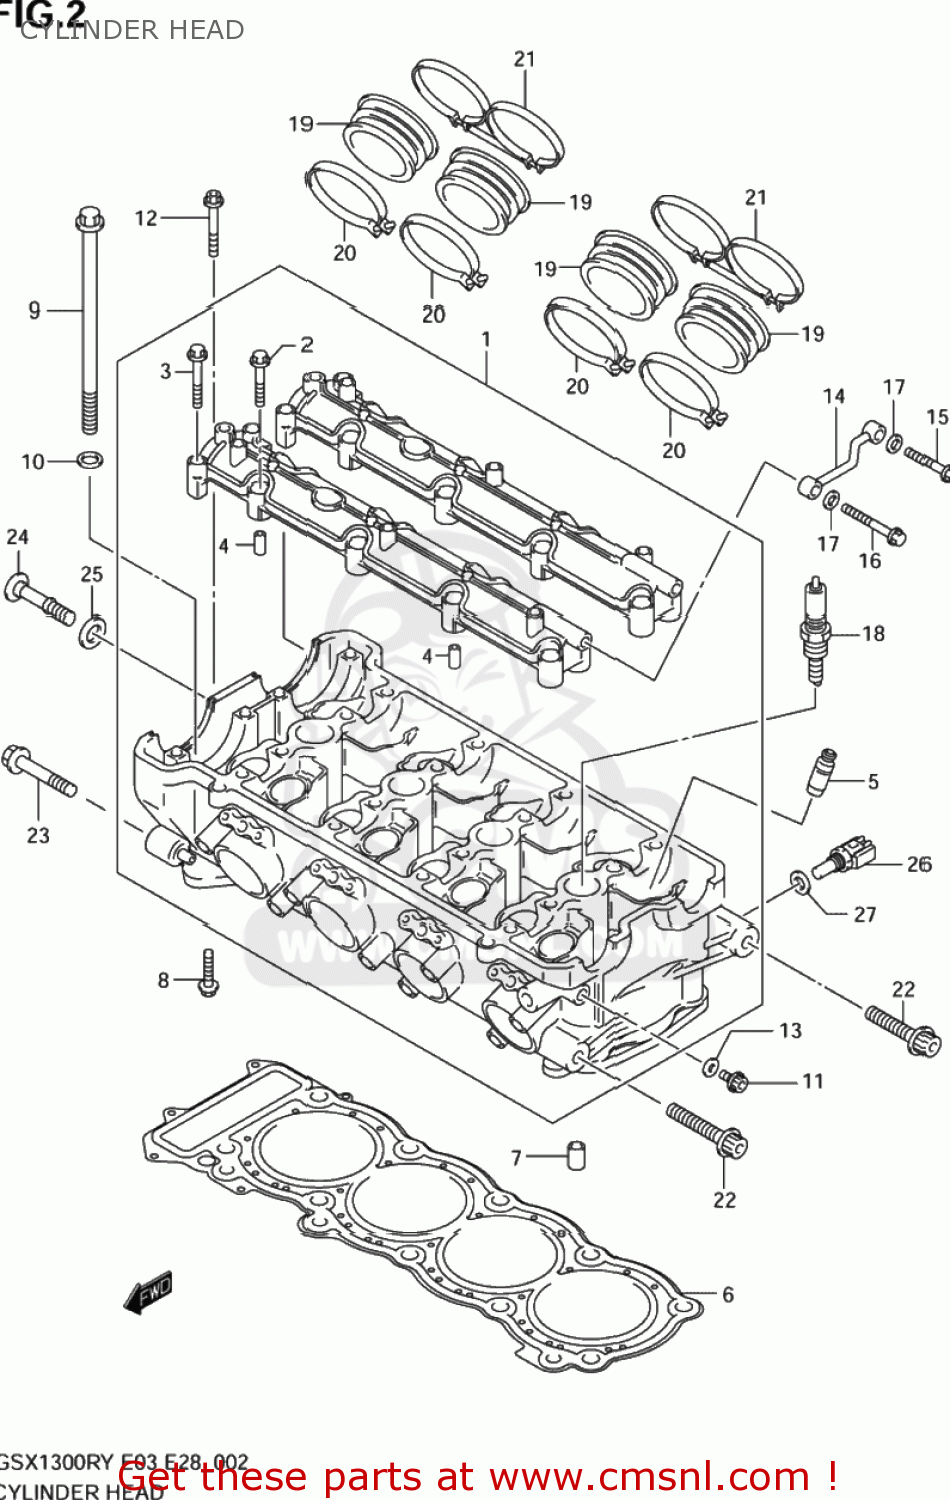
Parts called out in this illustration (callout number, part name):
1	HEAD ASSY,CYLINDER
2	BOLT(6X39)
3	BOLT(6X45)
4	PIN(6.2X8X16)
5	GUIDE,VALVE
6	GASKET,CYLINDER HEAD (NAS)
7	PIN
8	BOLT
9	BOLT(10X175)
10	WASHER(10.5X19X2)
11	BOLT
12	BOLT,CYL.OIL P
13	GASKET(5.8X13X1.2) (NAS)
14	PIPE,CYLINDER HEAD OIL
15	BOLT
16	BOLT (6X45)
17	WASHER
18	PLUG,SPARK(CR8E)
19	PIPE,INTAKE
20	CLAMP
21	CLAMP,INTAKE P
22	BOLT
23	BOLT
24	BOLT,CYL HEAD SIDE FACE
25	WASHER,HEAD COVER
26	SENSOR,WATER TEMP
27	GASKET(12X17X1) (NAS)
